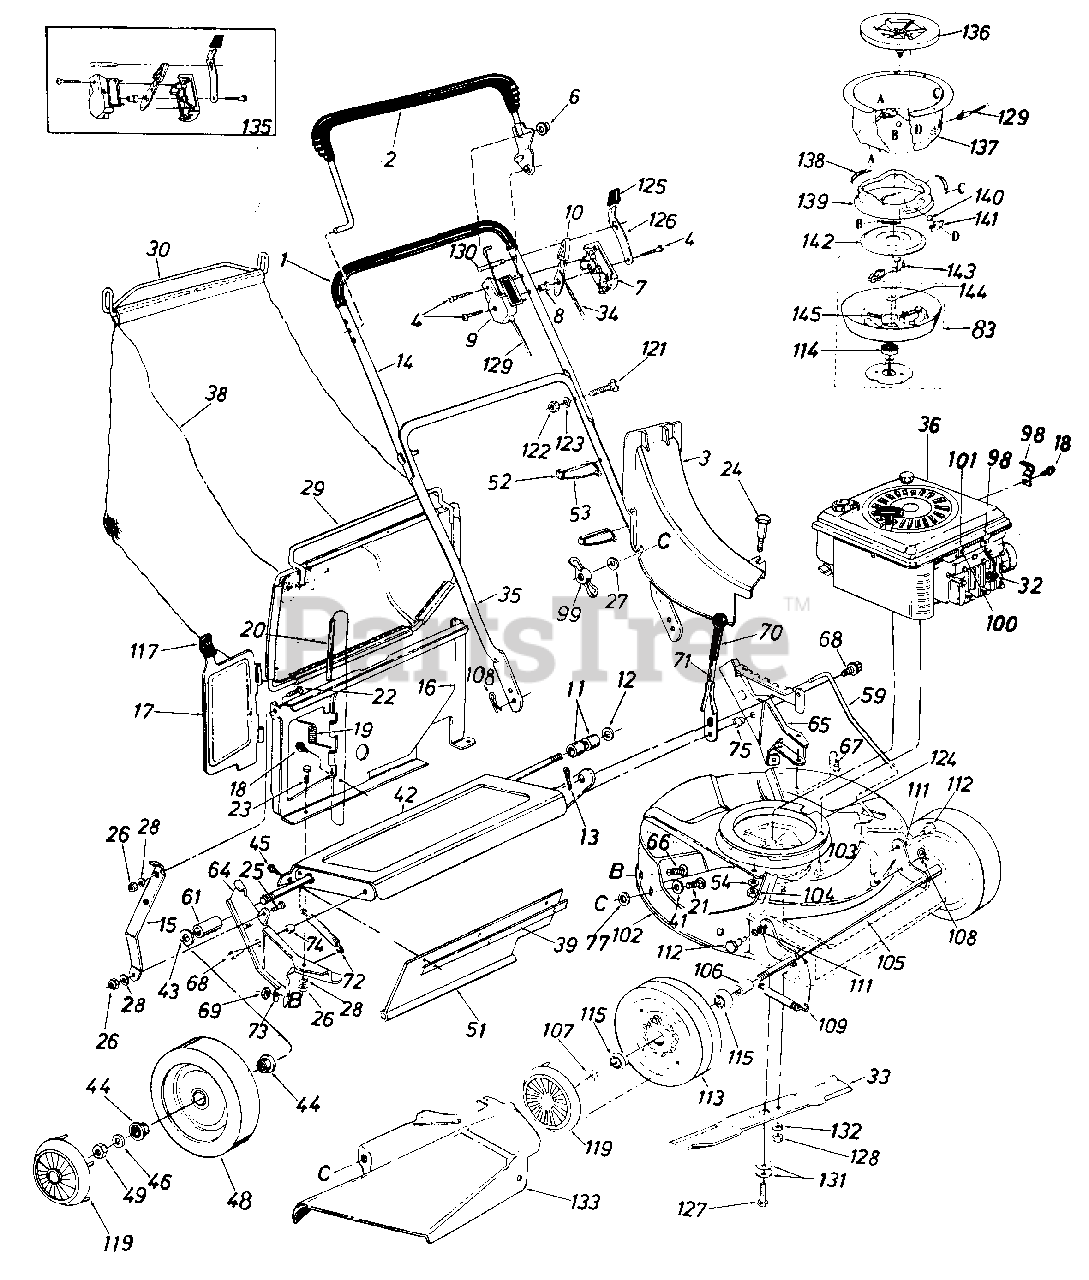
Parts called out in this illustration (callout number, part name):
1	Grip
2	Control Handle Ass'y. L.H.
3	Top Discharge Chute Ass'y.
4	Truss Mach. Scr. #12 x 1.50" Lg.
7	Control Panel Half
8	Control Disc Pin
9	Clutch Panel Half
10	Throttle Control Lever
11	Spacer .526" I.D. x .690" O.D. x .640" Lg.
12	Fl-Wash. .531" I.D. x .930" O.D.
13	Cotter Pin 3/32" Dia. x .75" Lg*
14	Upper Handle Chrome
15	Panel Support Brkt.
16	Top Catcher Panel
17	Top Door
18	Hex "B" Tap Scr. #10 x .38" Lg.
19	Torsion Spring .20" I.D. x 1.14" Lg.
20	Pivot Pin .187" Dia. x 7.25" Lg.
21	Carriage Bolt 1/4-20 x .62"*
22	Truss Mach. Scr. 1/4-20 x 1/2" Lg.
23	Hex Bolt 1/4-20 x .50" Lg.*
24	Shld. Bolt .312" Dia. x .18" Lg. Special
25	Truss Mach. Scr. 1/4-20 x .62" Lg.
26	Hex Nut 1/4-20 Thd.*t
27	Fl-Wash. .280" I.D. x .620" O.D.
28	L-Wash. 1/4" I.D.*
29	Front Grass Catcher Frame
30	Grass Catcher Handle
32	Spark Plug Insulator
34	Throttle Control Wire 58"
35	Lower Handle Chrome
36	Engine
38	21" Top Discharge Grass Bag
39	Retaining Strip
41	Fl-Wash. .344" I.D. x .62" O.D.
42	Rear Axle Ass'y.
43	Fl-Wash. .531" I.D. x .930" O.D.
44	Flange Ball Bearing 1/2" I.D.
45	Hex AB-Tap Scr. 1/4 x .62"
46	Fl-Wash. .531" I.D. x .930" O.D.
48	Rear Wheel Ass'y. Comp. 8 x 1.75
49	Hex L-Nut 1/2-20 Thd.
51	Rear Flap 3.75" x 17.30" Lg.
52	Cable Anchor
54	L-Wash. 1/4" I.D.
59	Height Adj. Rod
61	Spacer .513" I.D. x .703" O.D. x .690" Lg.
64	R.H. Handle Wheel Brkt. Ass'y.
65	L.H. Handle Wheel Brkt. Ass'y.
66	Carriage Bolt 5/16-18 x .62"*
67	Hex Wash. Hd. B-Tap Scr. 5/16-18
68	Hex Wash. Hd. TT-Tap Scr. 3/8-16
69	Hex Nut 5/16-18 Thd.
71	Height Adj. Lever
72	Extension Spring .50" O.D. x 3.80" Lg.
73	Bell-Wash. .345" I.D. x .88" O.D.
74	Spacer .385" I.D. x .502" O.D. x .270" Lg.
75	Shld. Spacer .500" Dia. x .100
77	Bolt Retainer 1/4 x .50" O.D.
83	Clutch Blade Housing Ass'y.
98	Throttle Control Cable Clip
100	Hex B-Tap Scr. #10 x .62" Lg.
101	Casing Clamp
104	Speed Nut 1/4-20 U-Type
105	Front Axle Ass'y.
106	Sleeve .526" I.D. x .690" O.D. x .880" Lg.
107	Hex L-Nut 1/2-20 Thd.
108	Intern. Cotter Pin 5/16" Dia.
109	Extension Spring .50" O.D. x 3.20" Lg.
111	Intern. L-Wash. 3/8 x .56" O.D.
112	Shld. Bolt .623" Dia. x .425
113	Front-Wheel Ass'y. Comp 7 x 1.75
114	Ball Brg. .669" I.D. x 1.574
115	Flange Ball Bearing 1/2" I.D.
117	Door Grip x 2.5
119	Hub Cap Plastic
121	Curved Carr. Bolt 5/16-18 x 1.38" Lg.
122	Hex Nut 5/16-18 Thd*
123	L-Wash. 5/16" I.D*
124	Blade Brake Clutch Comp.
125	Spring Lever Knob
126	Lockout Spring
127	Hex Cent. L-Bolt 3/8-24 x 2.00" (Grade 8)
128	Hex Nut 3/8-24 Thd. (Grade 8)
129	BBC Clutch Cable 46"
130	Lock Pin .314" Dia. x 1.75"
131	Bell-Wash. .400" I.D. x .88" O.D.
132	L-Wash. 3/8" I.D*
133	Side Chute Deflector
135	Kit Control Housing Comp.
137	Clutch Housing
138	Extension Spring .35" O.D. x 1.75" Lg.
139	Brake Cup Cone
140	Steel Ball .500" Dia.
142	Clutching Cone
143	Hex Tap L-Scr. 1/4-20 X .75"
144	Fl-Wash. .690" I.D. x 1.060" O.D.
145	Compression Spring .35" O.D. x 2.00" Lg.
